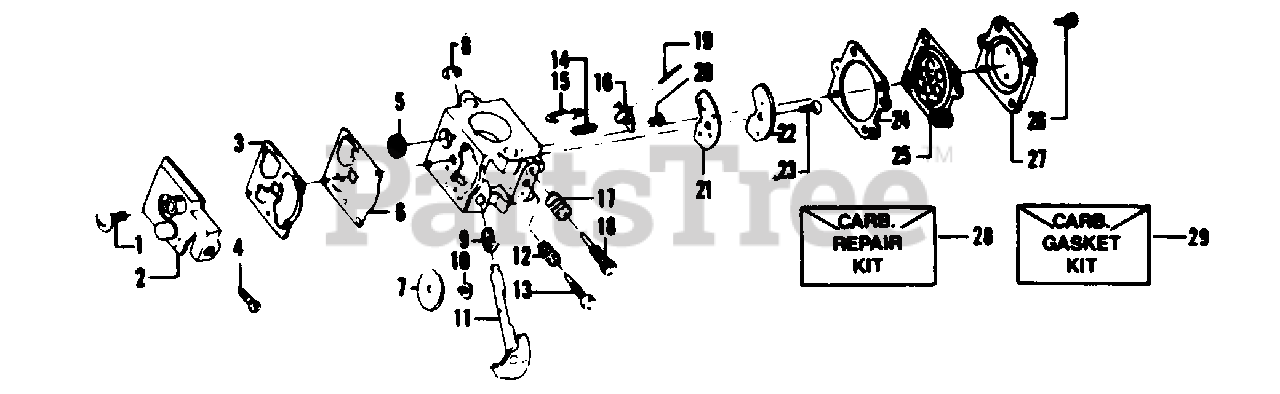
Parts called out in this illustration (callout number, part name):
1	Screw - Pump Cover
2	Pump Cover Ass'y (Inc. #4)
3	Gasket - Pump
4	Screw - Idle Adjustment
5	Screen - Inlet
6	Diaphragm - Pump
7	Valve - Throttle
8	Clip - Throttle Shaft
9	Spring - Throttle Return
10	Screw - Throttle Valve
11	Shaft Assembly - Throttle
12	Spring - Idle Needle
13	Needle - Idle
14	Spring - Metering Lever
15	Valve - Inlet Needle
16	Lever - Metering
17	Spring - Hi Speed Needle
18	Needle - Hi Speed
19	Pin - Metering Lever
20	Screw - Metering Lever Pin
21	Gasket - Circuit Plate
22	Plate - Circuit
23	Screw - Circuit Plate
24	Gasket - Metering Diaphragm
25	Diaphragm Assembly - Metering
26	Screw Assembly - Metering Cover & Throttle Shaft Clip
27	Cover - Metering Diaphragm
28	Kit - Carb. Kwik Repair Kit
29	Kit - Carb. Gasket / Diaphragm
